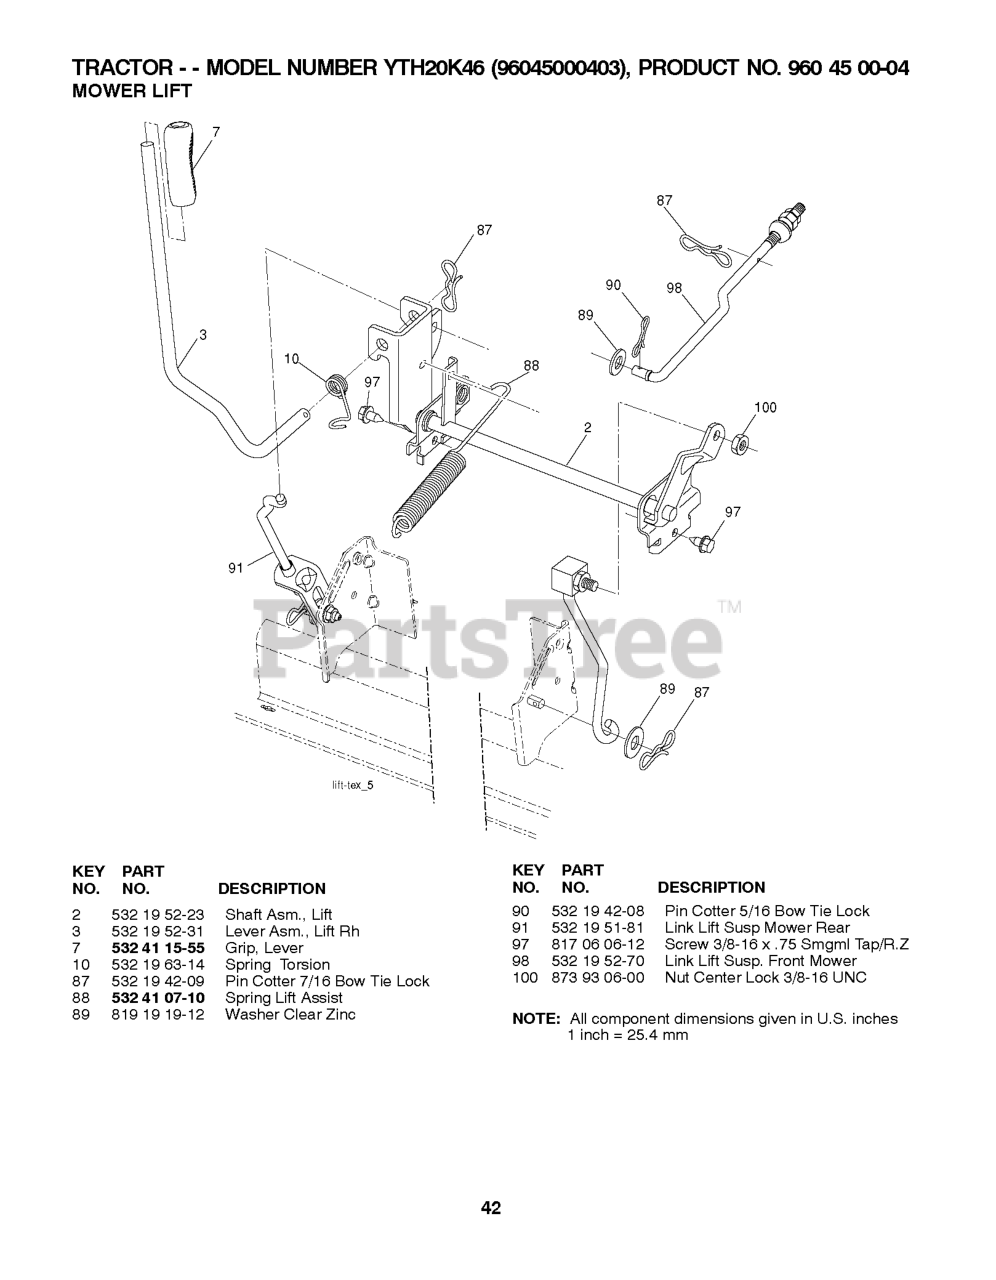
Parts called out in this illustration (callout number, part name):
2	SHAFT.ASM.LIFT.CROSS.H
3	LEVER.LIFT.HANDLE.LT
7	GRIP.HANDLE.LIFT.PVC.BLACK
10	SPRING.TORSION.LIFT.HANDLE
87	PIN.COTTER.7/16.BOW TI.
88	SPRING.LIFT.ASSIST
89	WASHER.CLEAR.ZINC
90	PIN.COTTER.5/16.BOW TI
91	LINK.ASM.LIFT.REAR
97	SCREW 3/8-16X3/4
98	LINK.ASM.SUSP.FRONT.MW
100	LOCKNUT
